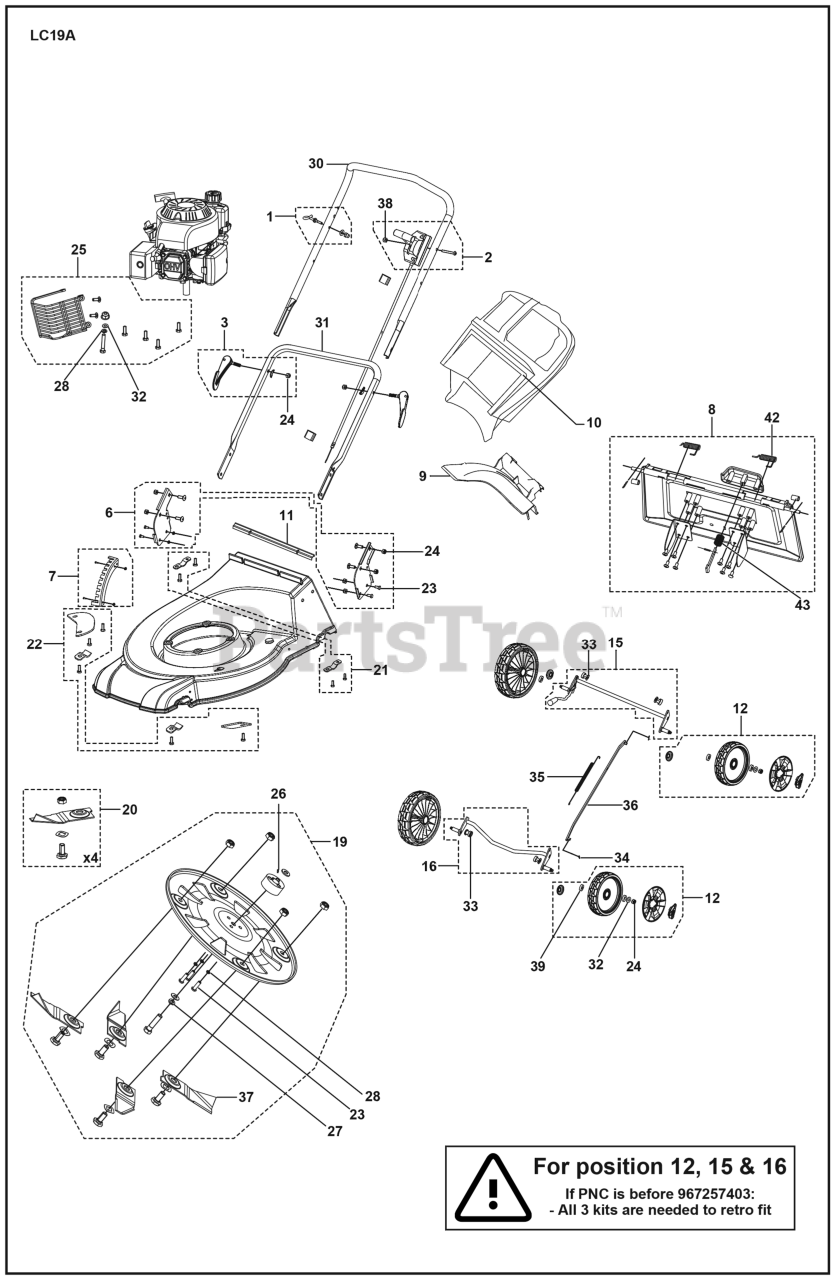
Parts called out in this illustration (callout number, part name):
24	LOCKNUT M8
27	Spring Washer
28	WASHER SPRING LOCK WASHER WITH
38	LOCKNUT M6
